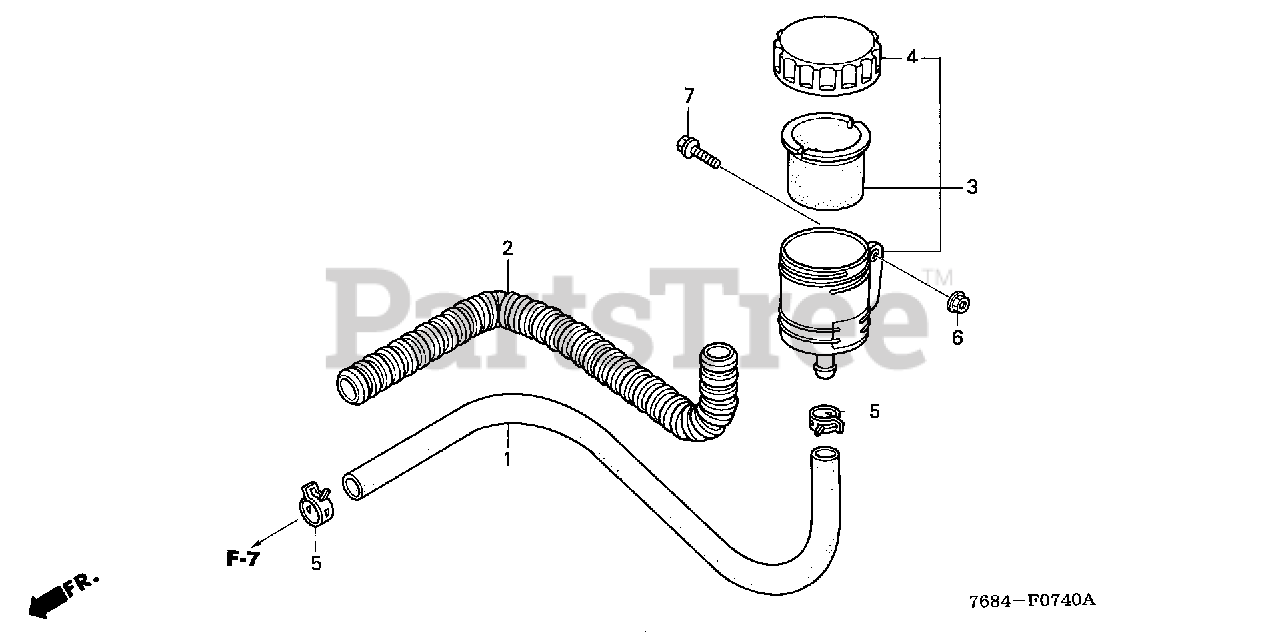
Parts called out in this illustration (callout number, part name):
2	PROTECTOR, OIL TUBE
3	TANK ASSY., OIL
4	BODY, OIL CAP
5	CLAMP D (19MM)
6	NUT, FLANGE (6MM)
7	BOLT, FLANGE (6X16)
